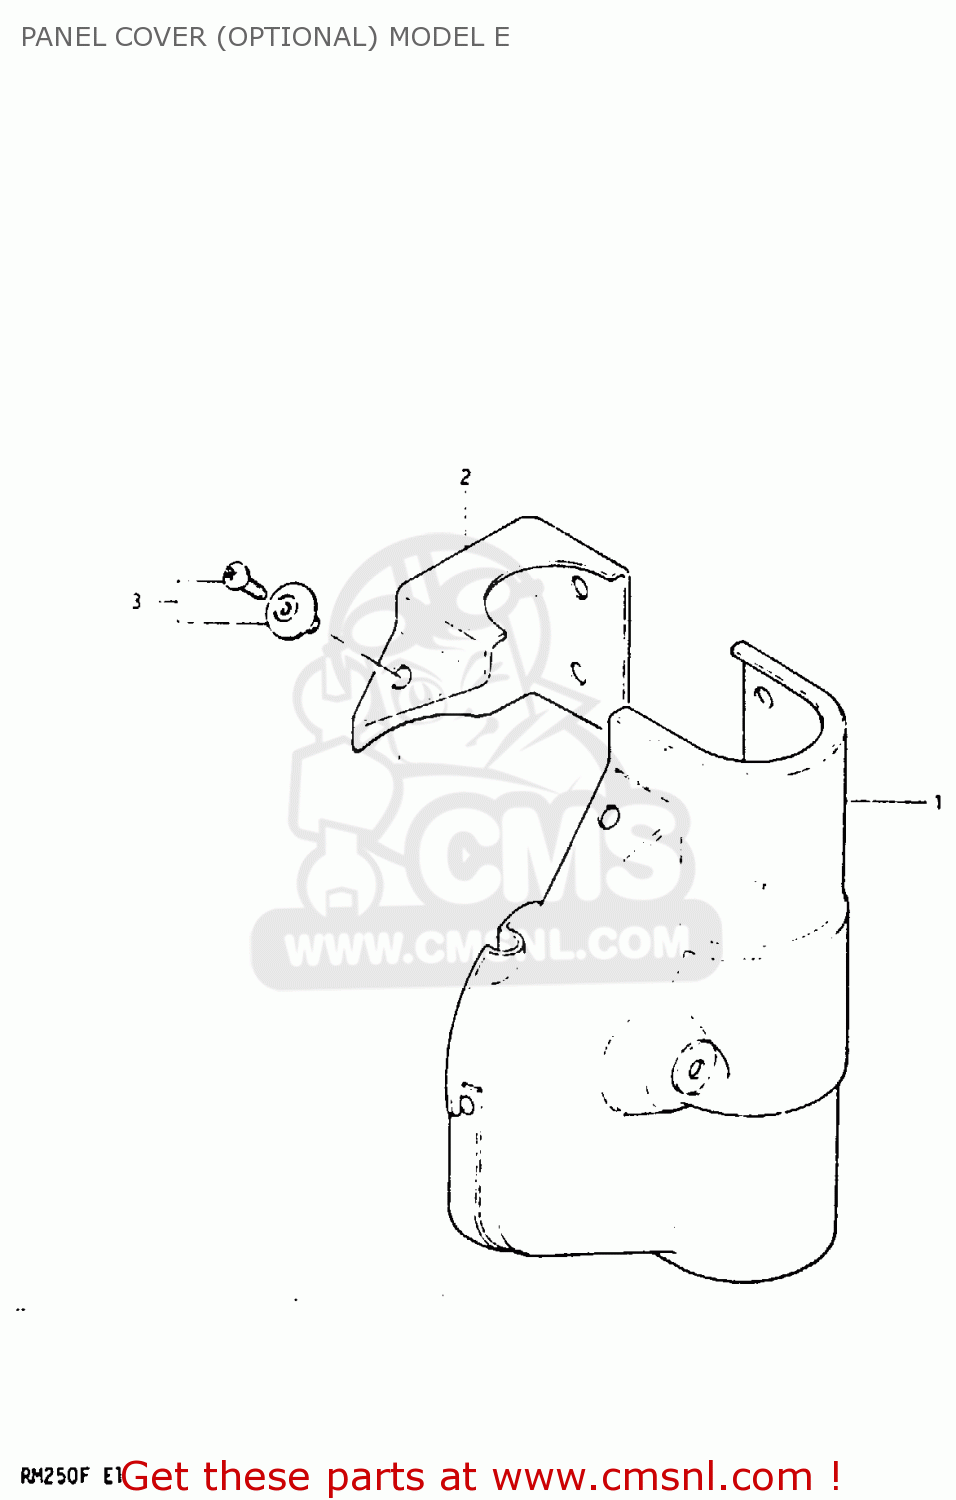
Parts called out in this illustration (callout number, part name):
1	COVER,FRONT HUB PANEL
2	CAP
3	CLIP(BLACK)
